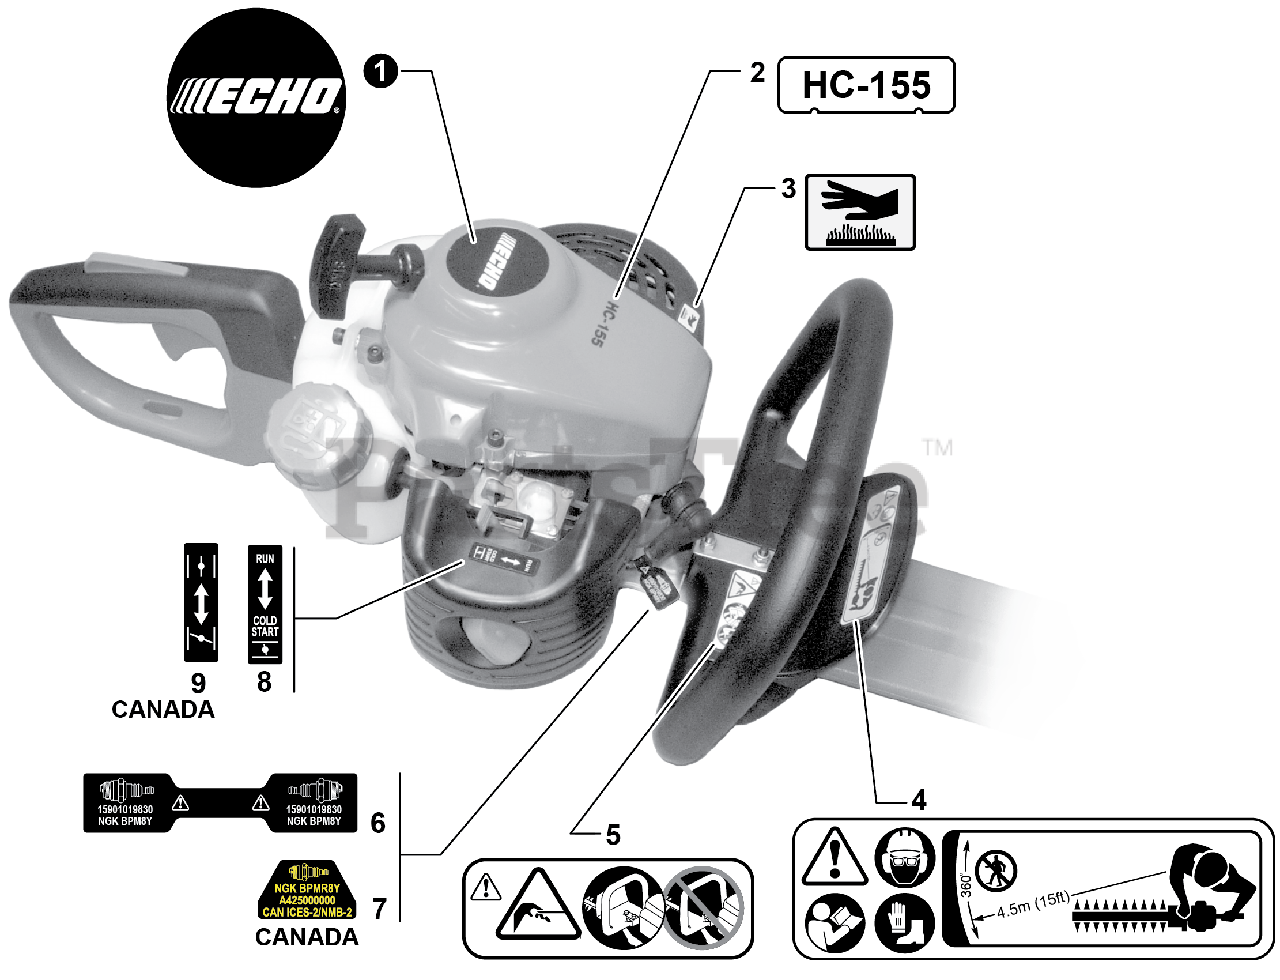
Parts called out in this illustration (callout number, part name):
1	LABEL, RECOIL STARTER
2	LABEL, MODEL - HC-155
3	LABEL, CAUTION - HOT
4	LABEL, CAUTION - ISO
5	LABEL, CAUTION
6	LABEL, SPARK PLUG - BPM8Y
7	LABEL, SPARK PLUG - BPMR8Y
8	LABEL, CHOKE
9	LABEL, CHOKE
